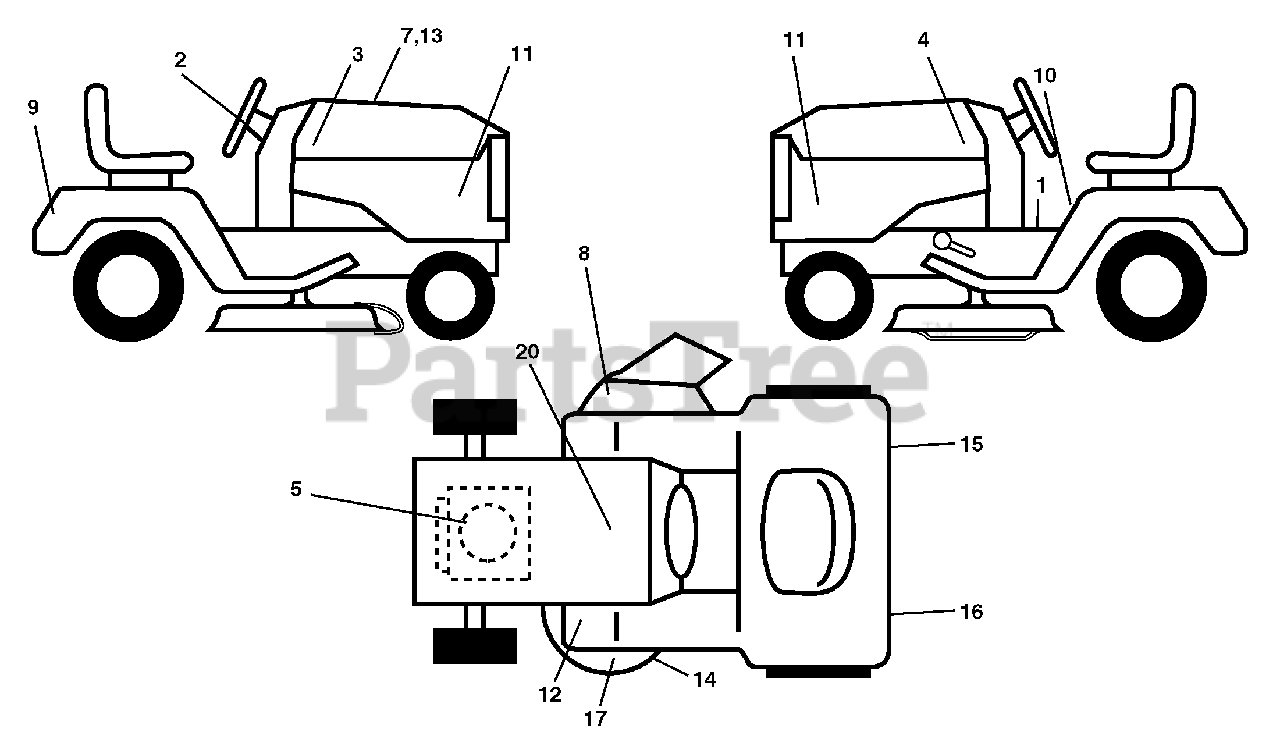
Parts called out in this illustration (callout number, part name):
1	Decal Oper Inst Hyd E/F
2	Decal Strg Wheel Logo
3	Decal Hood RH
4	Decal Hood LH
5	Decal Engine
7	Decal Repl. Parts
8	Decal Warning
9	Decal Fender Husq
10	Decal Fender Danger E/F
11	Decal Hood Sides
12	Decal Clutch/Brake
13	Decal Cust. Responsibilities
14	Decal V-Belt Schematic
15	Decal, Reflector, RH
16	Decal, Reflector, LH
17	Decal, Mower
20	Decal Bat Dan/Psn
